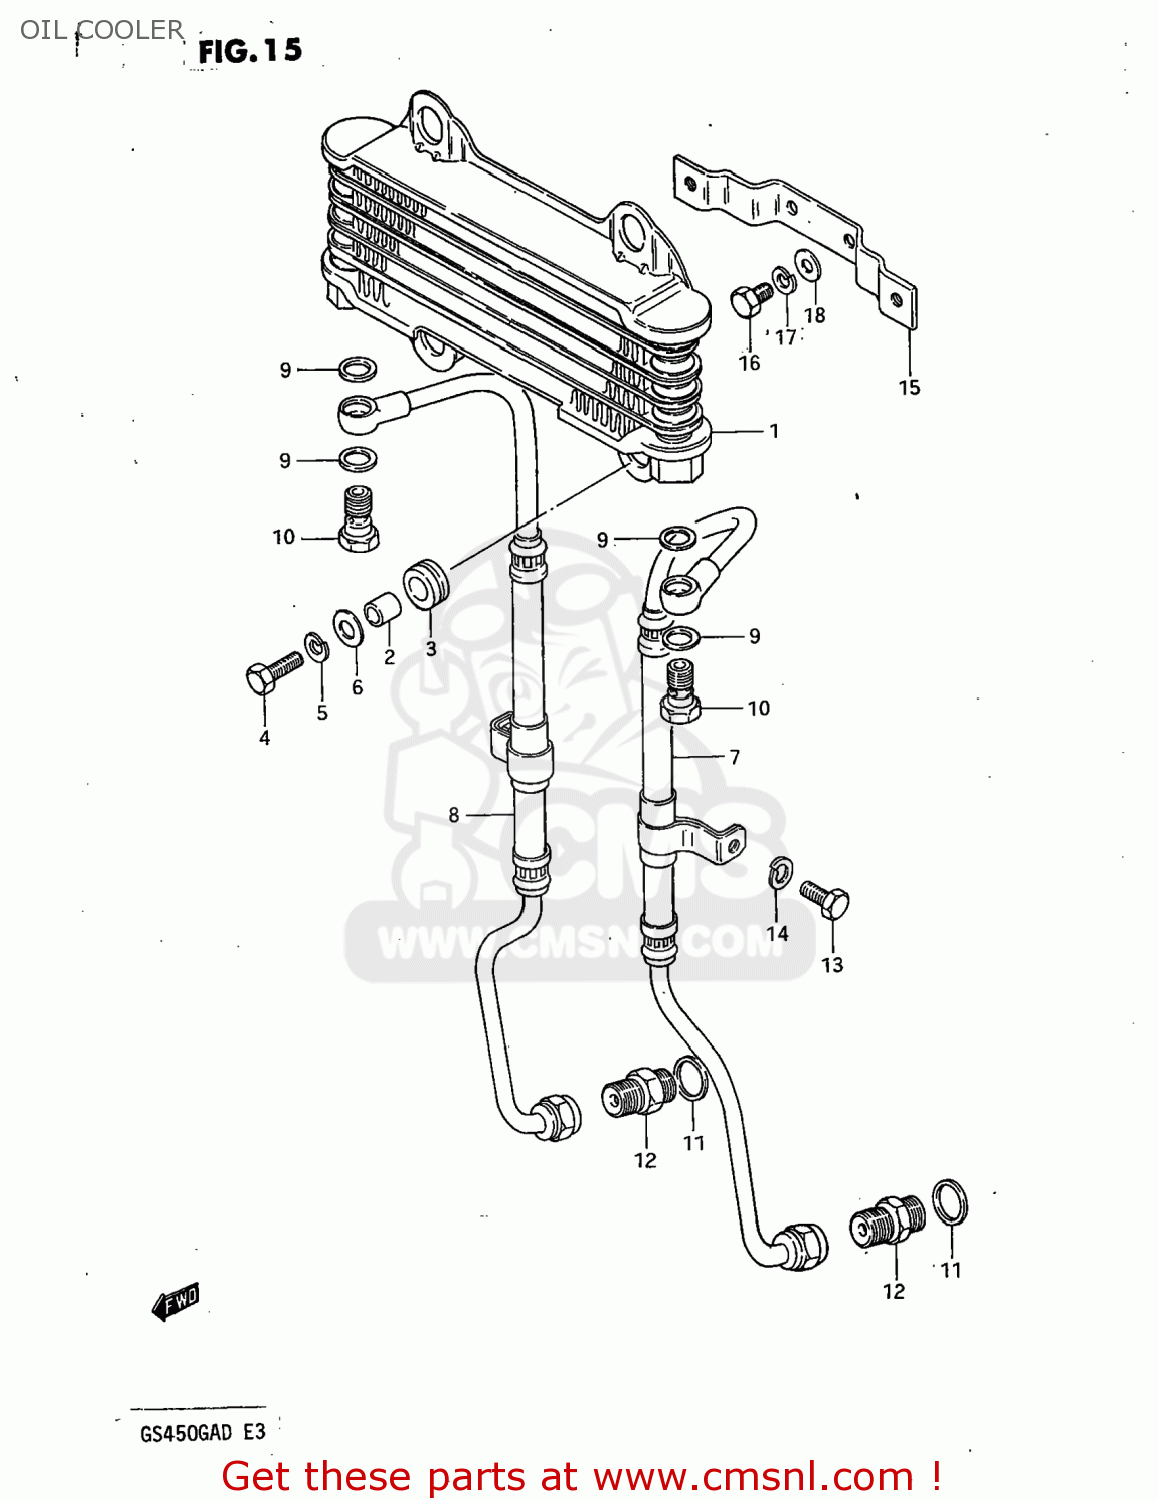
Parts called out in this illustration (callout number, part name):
1	COOLER ASSEMBLY,OIL
2	SPACER (6.8X10X10)
3	CUSHION
4	BOLT
5	LOCK WASHER
6	WASHER (6.5X18X1.6)
7	HOSE,ENGINE OIL,RIGHT
8	HOSE,ENGINE OIL,LEFT
9	GASKET(12X16.5X1.5) (NAS)
10	BOLT UNION
11	GASKET(14X20X1.5) (NAS)
12	BOLT UNION
13	BOLT
14	LOCK WASHER
15	BRACKET,OIL COOLER
16	BOLT
17	LOCK WASHER
18	WASHER
